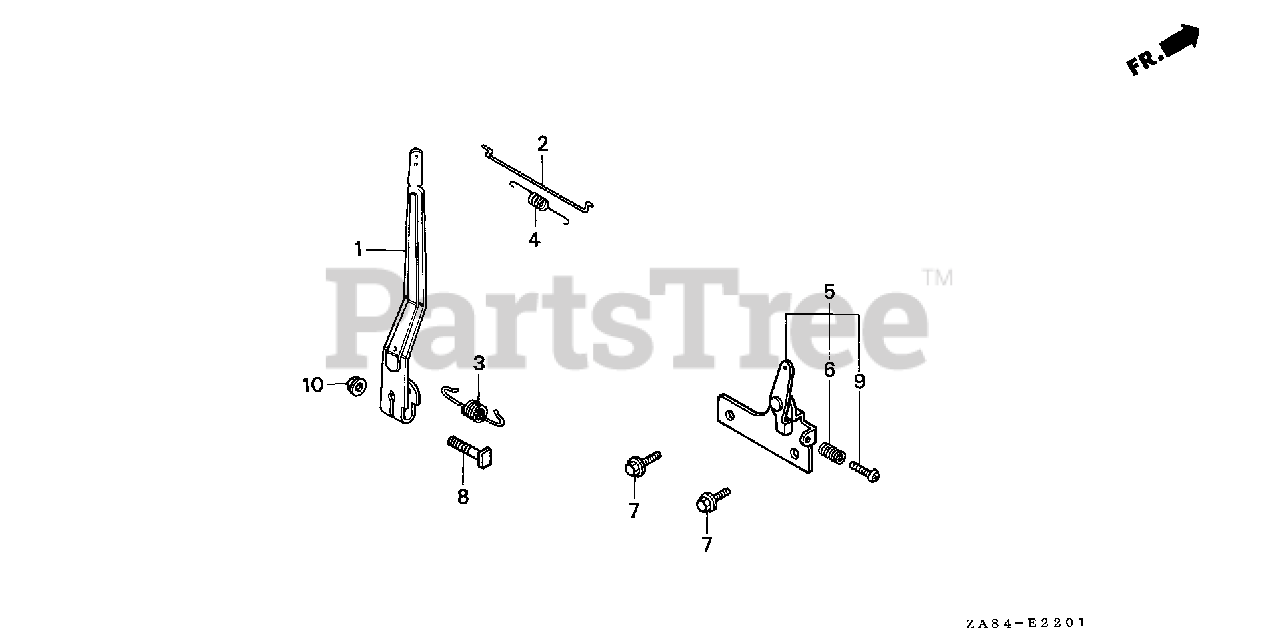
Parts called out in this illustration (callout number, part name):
1	ARM, GOVERNOR
2	ROD, GOVERNOR
3	SPRING, GOVERNOR
4	SPRING, THROTTLE RETURN
6	SPRING, CONTROL ADJUSTING
7	BOLT, FLANGE (6X12) (CT200)
8	BOLT, GOVERNOR ARM
9	SCREW, PAN (5X20)
10	NUT, FLANGE (6MM)
